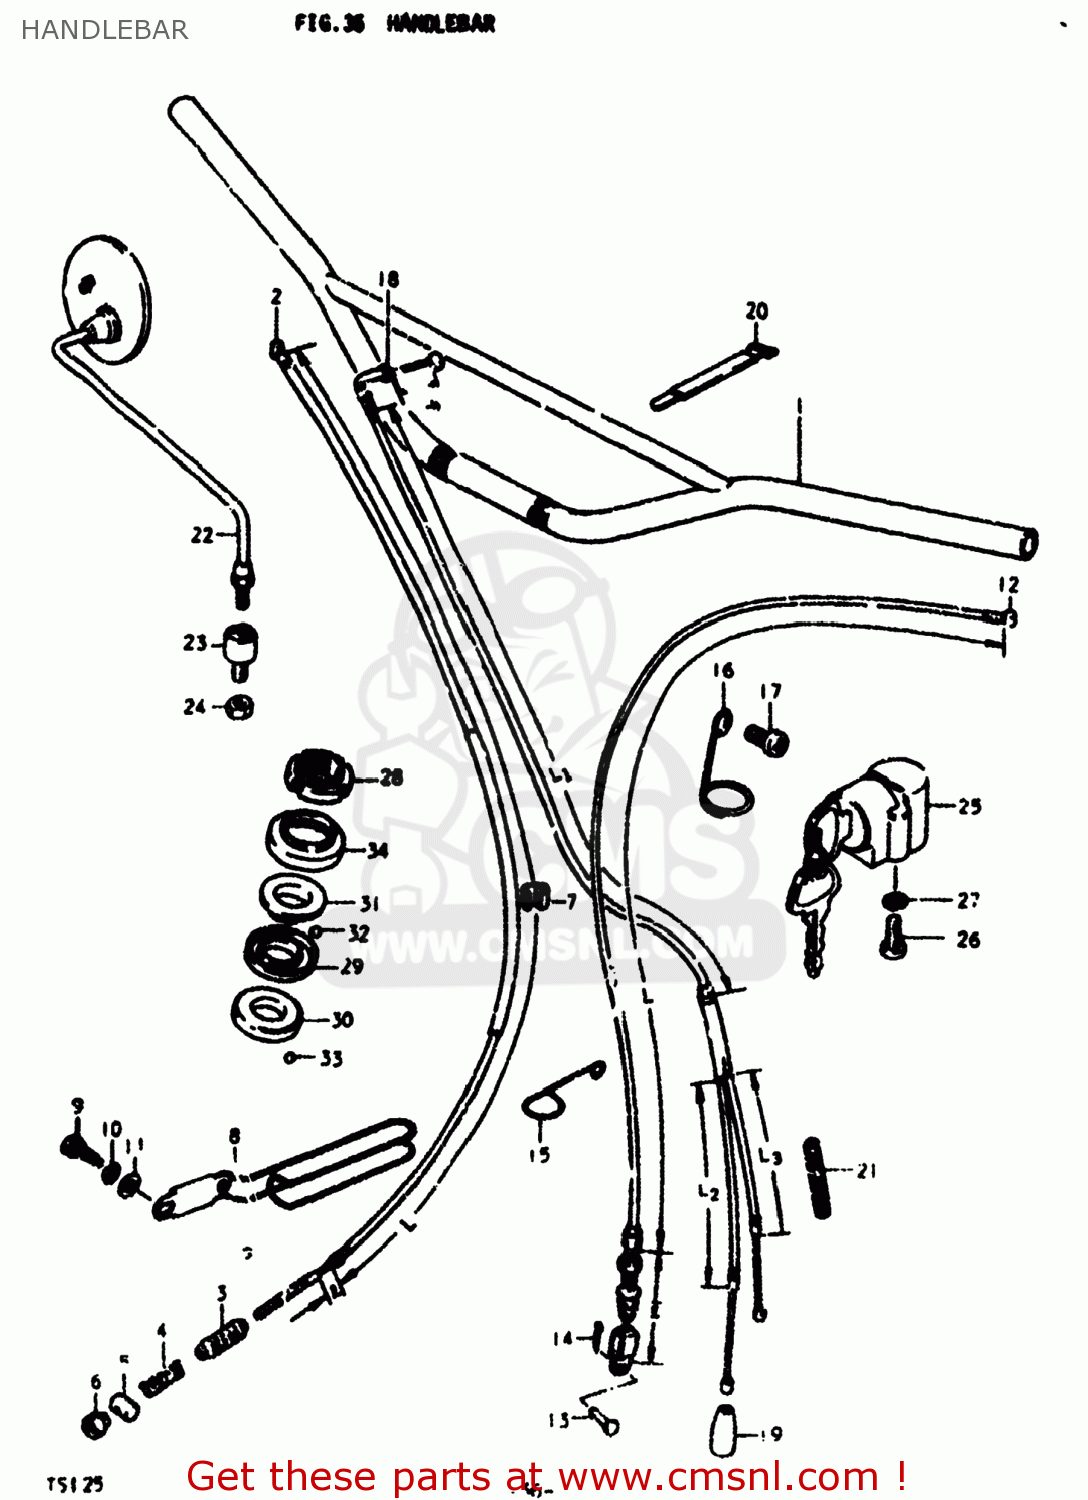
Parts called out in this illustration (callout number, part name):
1	HANDLEBAR
2	CABLE ASSEMBLY,FRONT BRAKE
3	SEAL,DUST(7X16X75)
4	SPRING
5	PIN,10X19
6	NUT
7	CLIP
8	GUIDE,CABLE
9	BOLT 8X12
10	LOCK WASHER
11	WASHER
12	CABLE ASSEMBLY,CLUTCH
13	PIN(L:15)
14	PIN
15	CLAMP,METER CABLE
16	CLIP,TACHOMETER CABLE
17	SCREW
18	CABLE ASSY,THROTTLE
19	SEAL,DUST(7X18X30)
20	CLAMP
21	PROTECTOR,CABLE
22	MIRROR ASSEMBLY,LEFT
23	CUSHION,REAR VIEW MIRROR
24	NUT
25	LOCK ASSEMBLY,STEERING
26	SCREW
27	LOCK WASHER
28	NUT,STEERING STEM(25X44X10)
29	RACE,STEERING INNER UPR
30	LACE,STEERING INNER LWR
31	RACE,STEERING OUTER UPR
32	BALL
33	BALL
34	DUST SEAL,STEERING UPR
